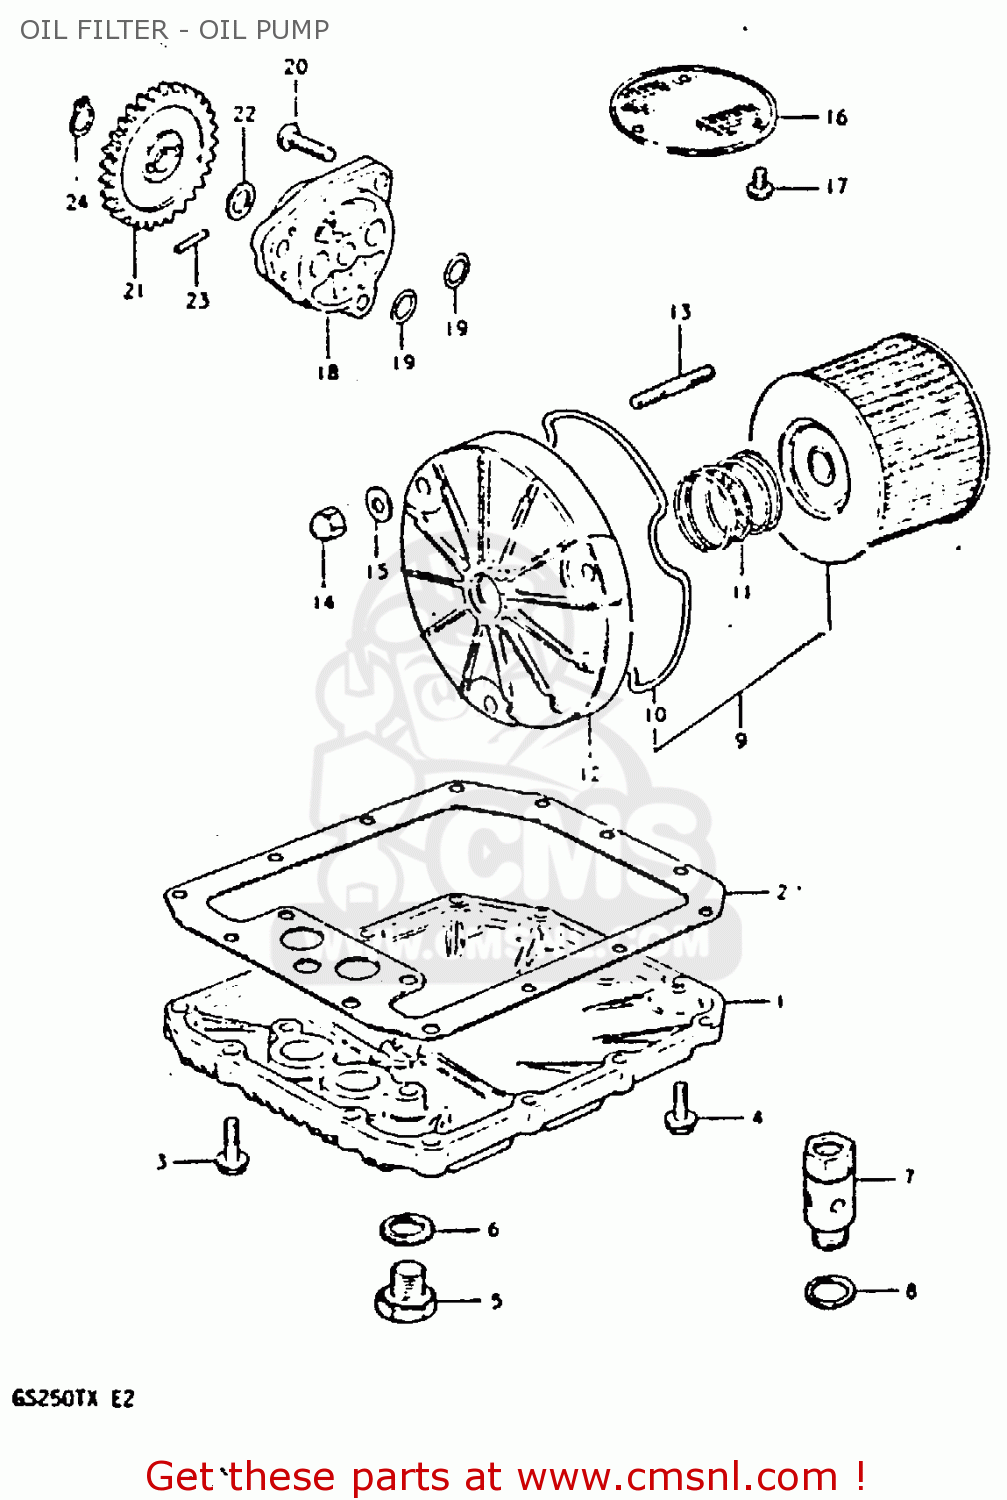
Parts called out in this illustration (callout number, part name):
1	PAN,OIL
2	GASKET,OIL PAN (MCA)
3	BOLT
4	BOLT,REAR
5	PLUG
6	GASKET(14X19.2X2) (NAS)
7	REGULATOR ASSEMBLY,ENGINE
8	WASHER
9	ENGINE OIL FILTER SET
10	O RING,OIL FILTER CHAMBER CAP
11	SPRING
12	CAP,ENGINE OIL FILTER
13	STUD 6X20
14	NUT
15	WASHER
16	STRAINER,ENGINE OIL
17	SCREW 6X12
18	PUMP ASSY,ENGINE OIL
19	O RING(D:1.9,ID:13)
20	SCREW
21	GEAR,OIL PUMP DRIVEN
22	SHIM
23	PIN(4X15.8)
24	CIRCLIP
